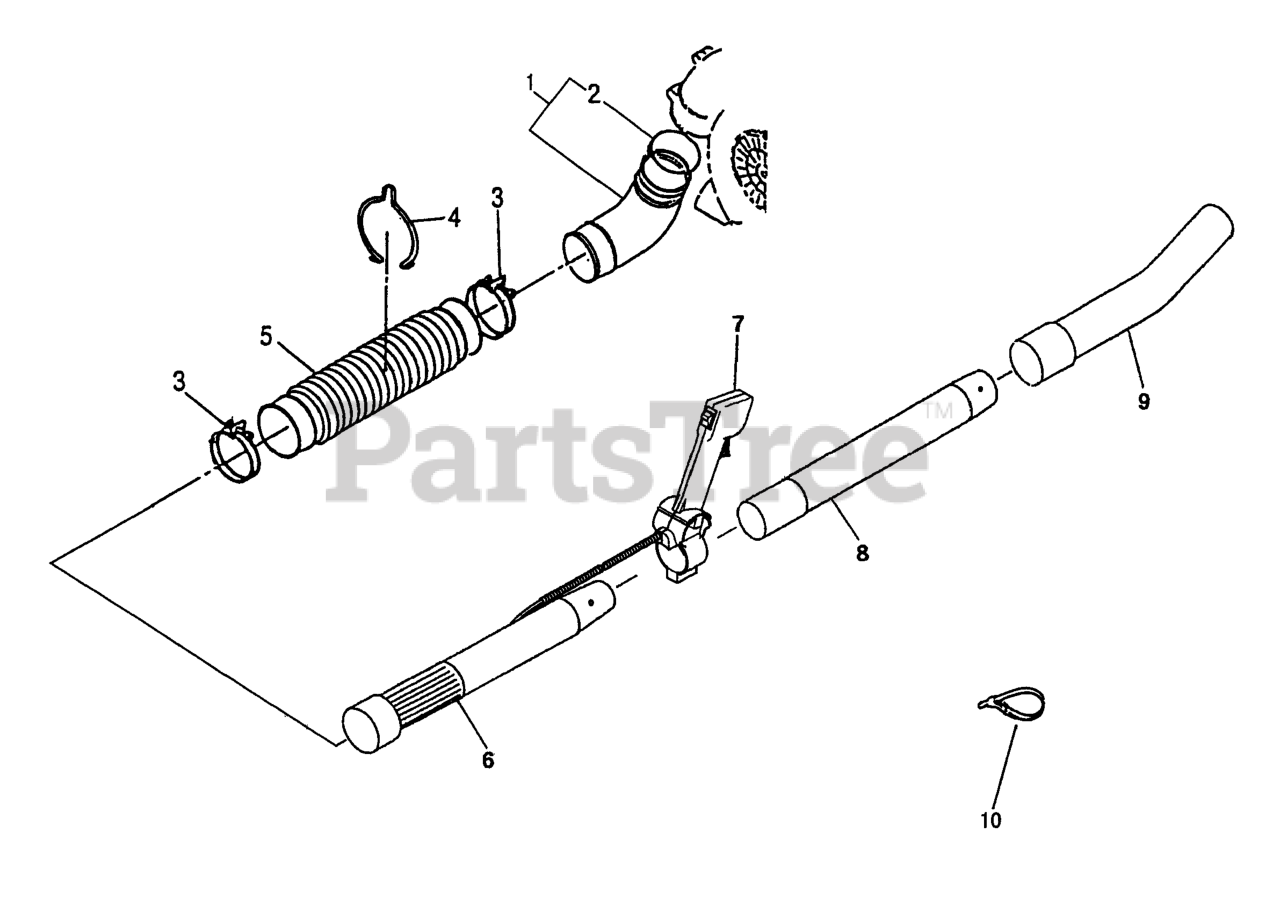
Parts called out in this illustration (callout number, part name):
1	ELBOW PIPE C.P.
2	O'RING
3	HOSE BAND
4	CLAMP
5	FLEX. PIPE 36084-101
6	BASE PIPE
7	THROTTLE ASSEMBLY
8	MIDDLE PIPE
9	BEND PIPE
10	BAND FR66820XX006
